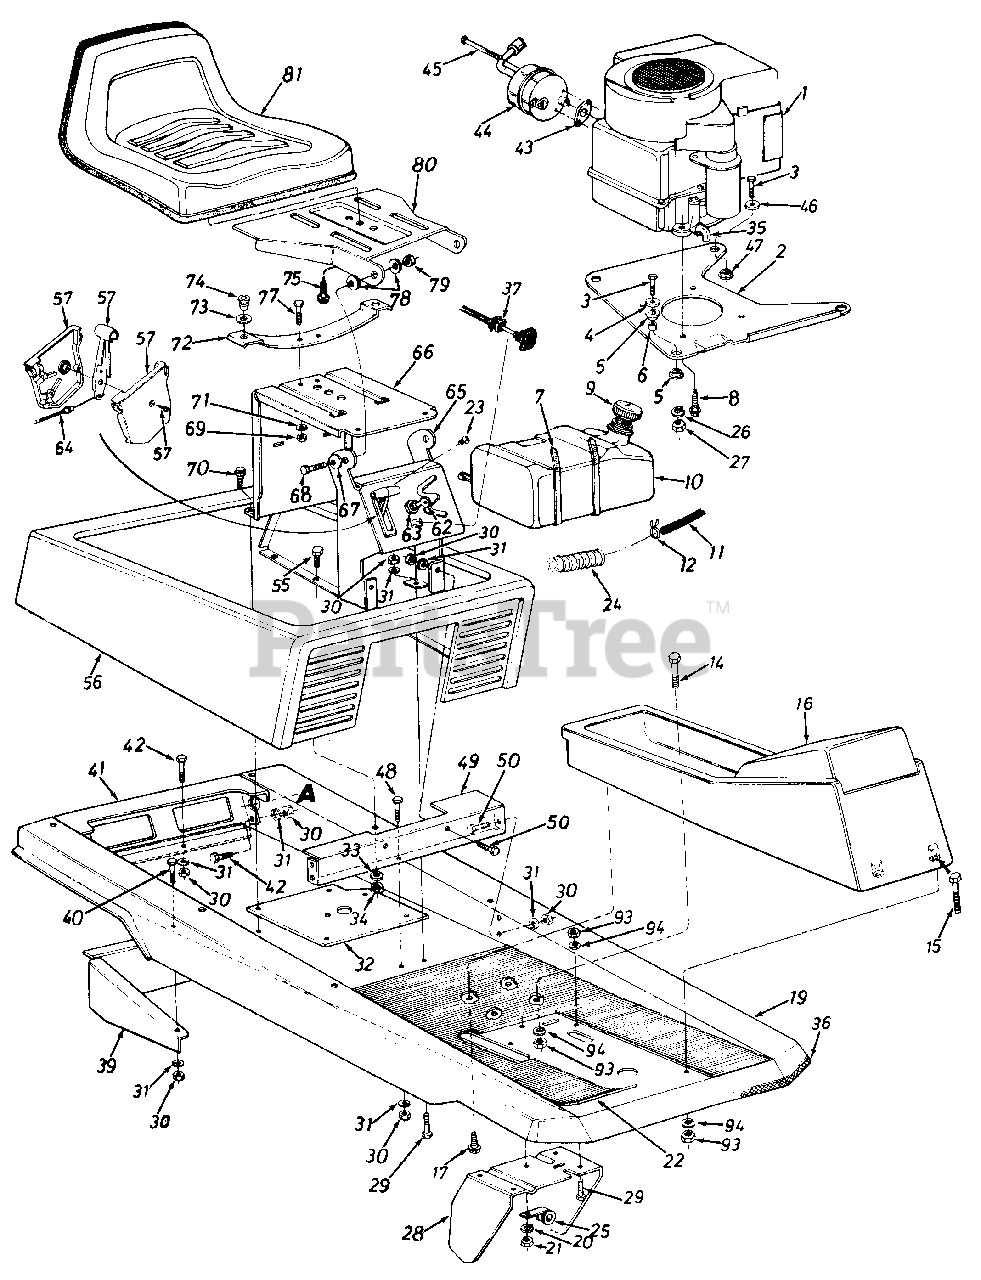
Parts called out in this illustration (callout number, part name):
1	Engine
2	Engine Mounting Plate
3	Hex Bolt 5/16-24 x 1.25" Lg.
4	Fl-Wash. .330" I.D. x 1.125" O.D.
5	Engine Mounting Grommet
6	Spacer .315" I.D. x .50" O.D. x .520" Lg.
7	Cable Tie 30.6 Lg.
8	Hex Wash. Hd. Self-Tap Scr. 3/8-16 x 1.25" Lg.
9	Gas Gauge
10	Fuel Tank
11	Gas Line
12	Hose Clamp-.406" Dia.
14	Hex Bolt 5/16-18 x 1.75" Lg.*
15	Hex Bolt 5/16-18 x 2.0" Lg.*
16	Front Console
17	Plastite Scr. 5/8 x 1.25"
19	Main Frame
20	L-Wash. 5/16" I.D.*
21	Hex Nut 5/16-18 Thd.*
22	Floor Mat
23	Truss Mach. AB-Tap Scr. #10 x .50" Lg.
24	Convoluted Conduit
26	L-Wash. 5/16" I.D.*
27	Hex Nut 5/16-24 Thd.*
28	Clutch-Brake Pedal Ass'y.
29	Hex Bolt 5/16-18 x .75" Lg*
30	Hex Nut 5/16-18 Thd.*
31	L-Wash. 5/16" I.D.*
32	Mounting Brkt. Variable Speed Pulley
33	L-Wash. 1/4" I.D.*
34	Hex Nut 1/4-20 Thd.*
35	90ø Elbow Male To Female
36	Trim Strip 18" Lg.
37	Choke Control
39	Transaxle Support Ass'y.
40	Hex Bolt 5/16-18 x .75" Lg.*
43	Exhaust Gasket (8 H.P.)
44	Muffler Ass'y. (8 H.P.)
45	Shld. Bolt (8 H.P.)
46	Fl-Wash. .330" I.D. x 1.25" O.D.
47	Flange Wash. .320" I.D. x .750" O.D.
49	Seat Support & Frame Brkt.
50	Hex Bolt 5/16-18 x .75" Lg.*
55	Hex Bolt 1/4-20 x .50" Lg.**
56	Engine Cover Ass'y.
57	Throttle Control Box Ass'y.
62	Ignition Key
63	Ignition Switch
64	Throttle Control Wire
65	Front Seat Bracket
66	Rear Seat Bracket
67	Bell-Wash. .345" I.D. x .88" O.D.
68	Hex Bolt 5/16-18 x .75" Lg.*
69	Hex Nut 5/16-18 Thd.*
70	Hex Self-Tap Scr. 5/16-18 x .75" Lg.
71	L-Wash. 1/4" I.D.*
72	Seat Spring
73	Fl-Wash. .531" I.D. x .930" O.D.
75	Hex Wash. Hd. Tap Scr. 3/8-16 x 3/4" Lg.
77	Hex Bolt 1/4-20 x .75" Lg.
78	Bell-Wash. .345" I.D. x .88" O.D.
79	Hex Cent. L-Nut 5/16-18 Thd.
80	Seat Pivot Bracket
81	Seat Ass'y. Comp.
93	Hex Nut 5/16-18 Thd.*
94	L-Wash. 5/16" I.D.*
15571-0629	PANEL-FRAM - SILVER FLAKE (0629)
15571-0638	PANEL-FRAM - MTD/TROY-BILT RED (0638)
